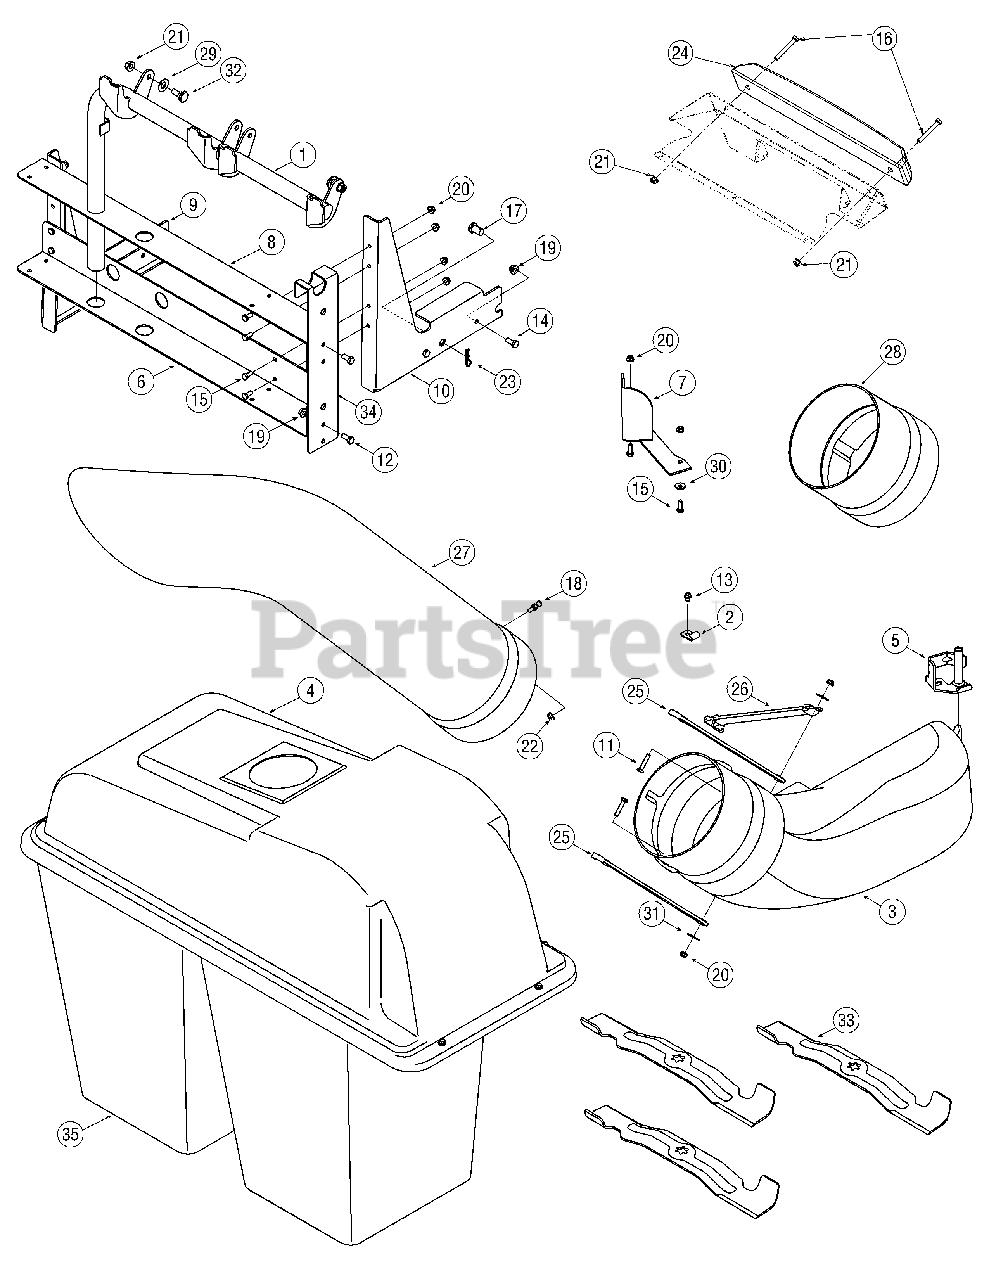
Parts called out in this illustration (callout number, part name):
2	Retainer Hook Bracket
3	Chute Elbow
4	Grasscatcher Cover Assembly
9	Catcher Mounting Bracket LH
10	Catcher Mounting Bracket RH
11	Hex Bolt 1/4-20 x 1.25 Gr5
12	Hex Bolt 5/16-18 x 1.00 Gr5
13	TT Screw 1/4-20 x 0.5
14	Hex Bolt 5/16-18 x .75 Gr5
15	Hex Bolt 1/4-20 x 0.75 Gr5
16	Hex Bolt 3/8-16 x 2.75 Gr5
17	Clevis Pin
18	Grasscatcher Pin
19	Flange Lock Nut, 5/16-18 GrF
20	Flange Lock Nut 1/4-20 GrF
21	Flange Lock Nut 3/8-16 GrF
22	Flange Lock Nut 1/4-20
23	Cotter Pin
24	Weight Bar
25	Chute Strap
26	Chute Strap
27	Chute Tube
28	Chute Extension
29	Bell Washer
30	Bell Washer
31	Flat Washer
32	Shoulder Screw 3/8-16
35	Grassbag Assembly
